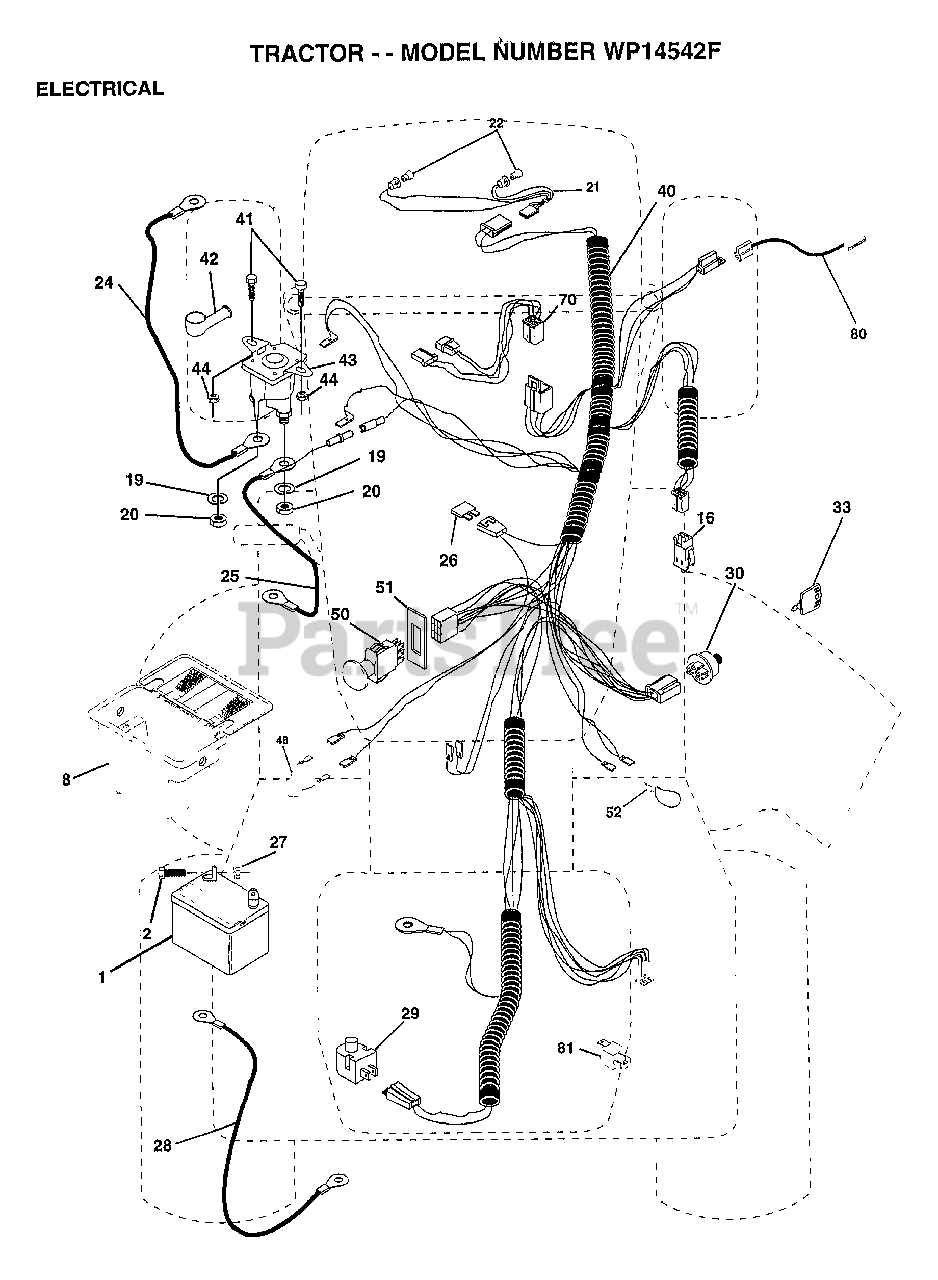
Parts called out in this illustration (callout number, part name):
2	BOLT LT
8	"CASE,BATTERY.MECH"
16	SWITCH INTERLOCK
20	NUT
21	HARNESS.ASM.LIGHT.W/4152J
22	HEADLAMP BULB
24	CABLE.BTRY.6GA.RD
25	CABLE.BTRY.6GA.38
26	FUSE.15 AMP
27	NUT
28	CABLE T
29	SWITCH.PLUNGER
30	SWITCH.IGN.
33	KEY MLD GEN DELTA
40	HARNESS
41	BOLT HXHD FIN
44	NUT HXKEP 1/4X20
48	ADAPTER AMMETER
50	SWITCH, PTO 3PDT BLACK DELTA 96
51	RING RETAIN PTO
52	PROTECTION LOOP
70	HARNESS.ENGINE.B&S
80	HARNESS.CLUT.EVX.
81	RELAY ASSY T
